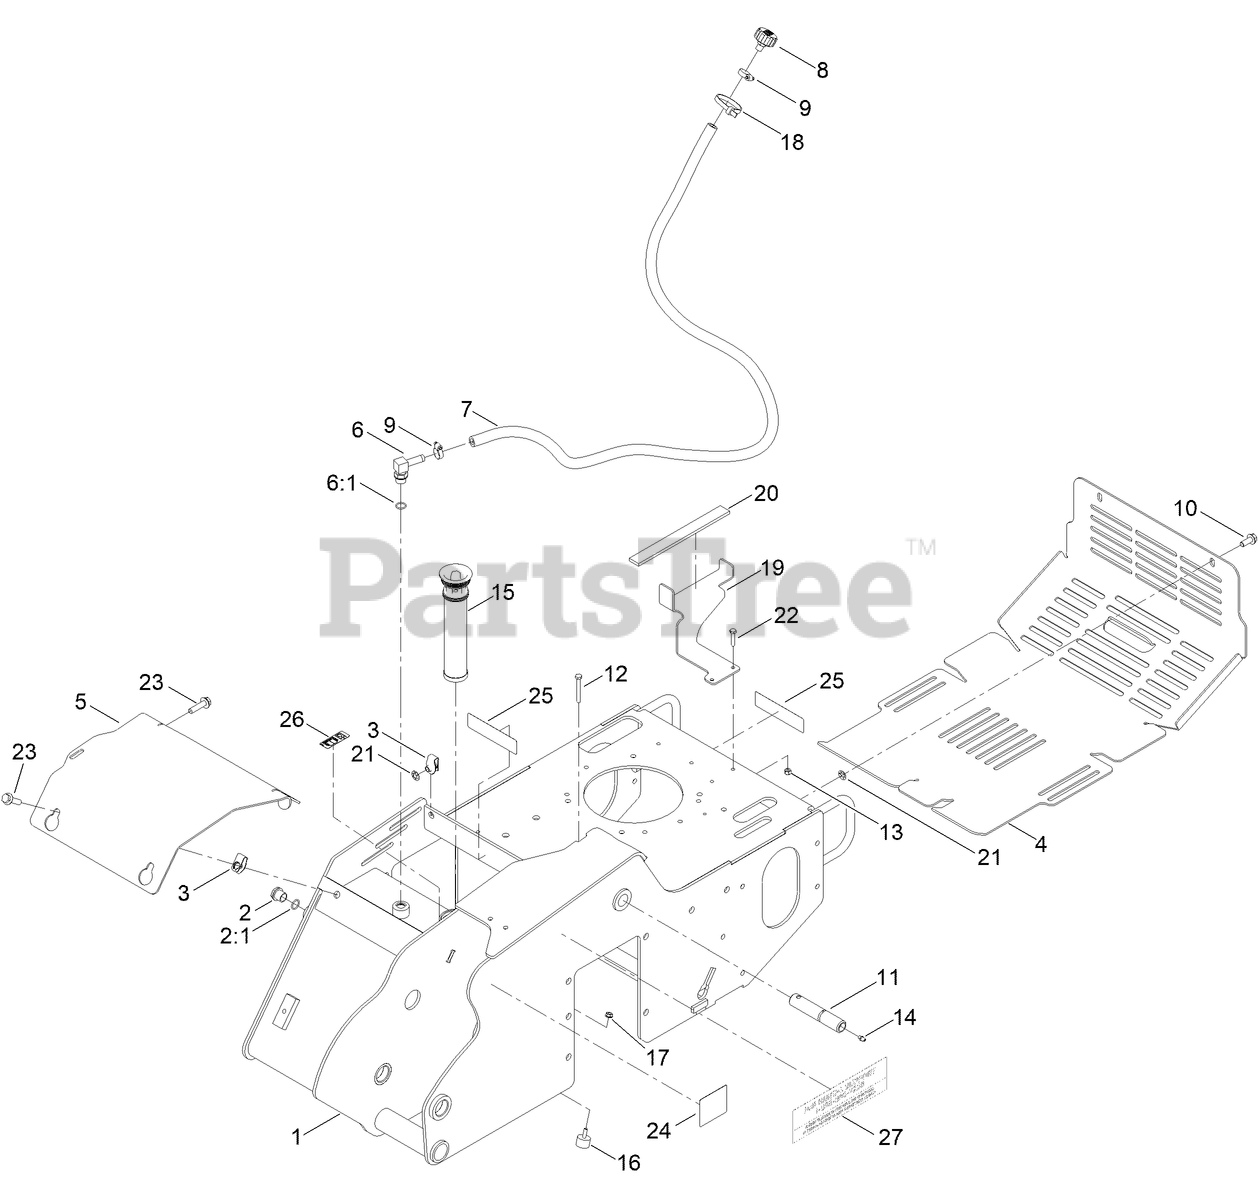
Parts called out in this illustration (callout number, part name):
1	MAIN FRAME ASM, [505-164]
2	SIGHT GLASS ASM
2:1	O-RING
3	NUT-CLIP, U
4	COVER-REAR
5	PLATE-COVER,FRONT
6	FITTING-ELBOW, 90
6:1	O-RING
7	HOSE-BREATHER
8	BREATHER
9	CLAMP-HOSE
10	SCREW-HHF
11	PIN-PIVOT
12	SCREW-HH
13	NUT-LOCK, NI
14	FITTING-GREASE
15	IN-TANK FILTER ASM
16	BUMPER
17	NUT-HF
18	TIE-CABLE
19	BRACKET-TANK
20	PAD-FOAM
21	NUT-PUSH
22	SCREW-HH
23	SCREW-HHF
24	DECAL-WARNING
25	DECAL-DANGER
26	DECAL-OIL, HYD
27	DECAL-CPER0002
